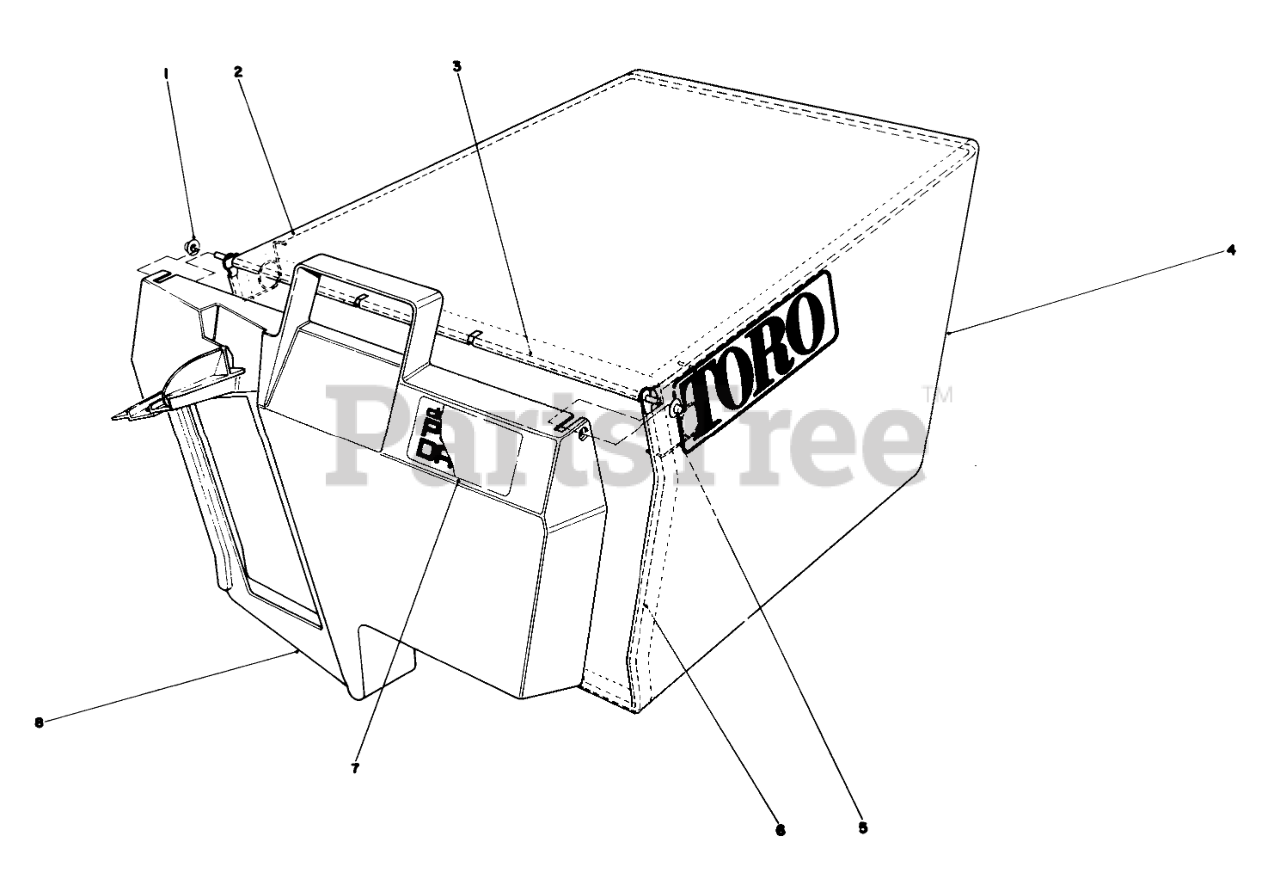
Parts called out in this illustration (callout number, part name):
1	NUT-PUSH
2	FRAME-BAG, UPPER
3	HINGE-DOOR, BAG
4	BAG-GRASS
5	SPRING
6	FRAME-BAG
7	BAG DOOR DECAL
8	DOOR-BAG
